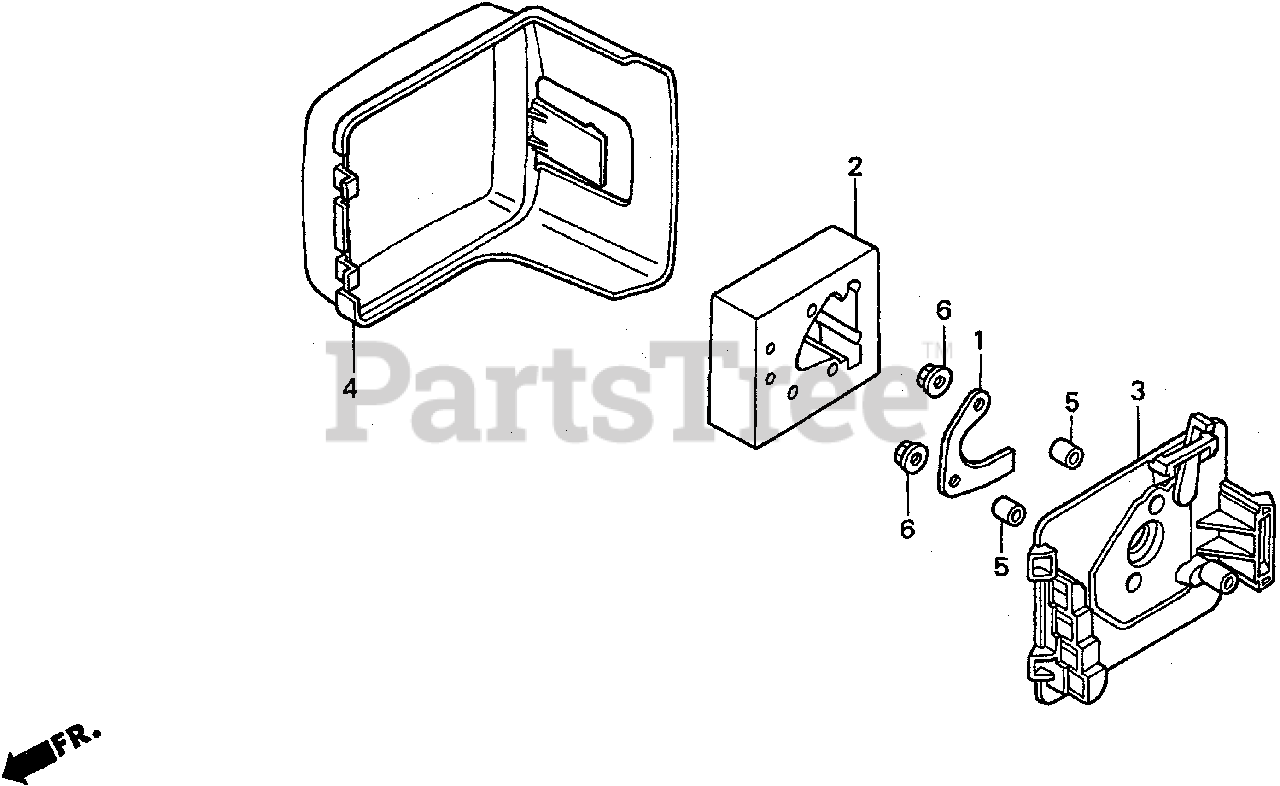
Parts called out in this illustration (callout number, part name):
1	PLATE, OIL TRAP
2	ELEMENT, AIR CLEANER (SEMI-DRY)
3	HOUSING COMP., AIR CLEANER *R8* (BRIGHT RED)
4	COVER, AIR CLEANER *R8* (BRIGHT RED)
5	COLLAR, AIR CLEANER
6	NUT, FLANGE (5MM)
